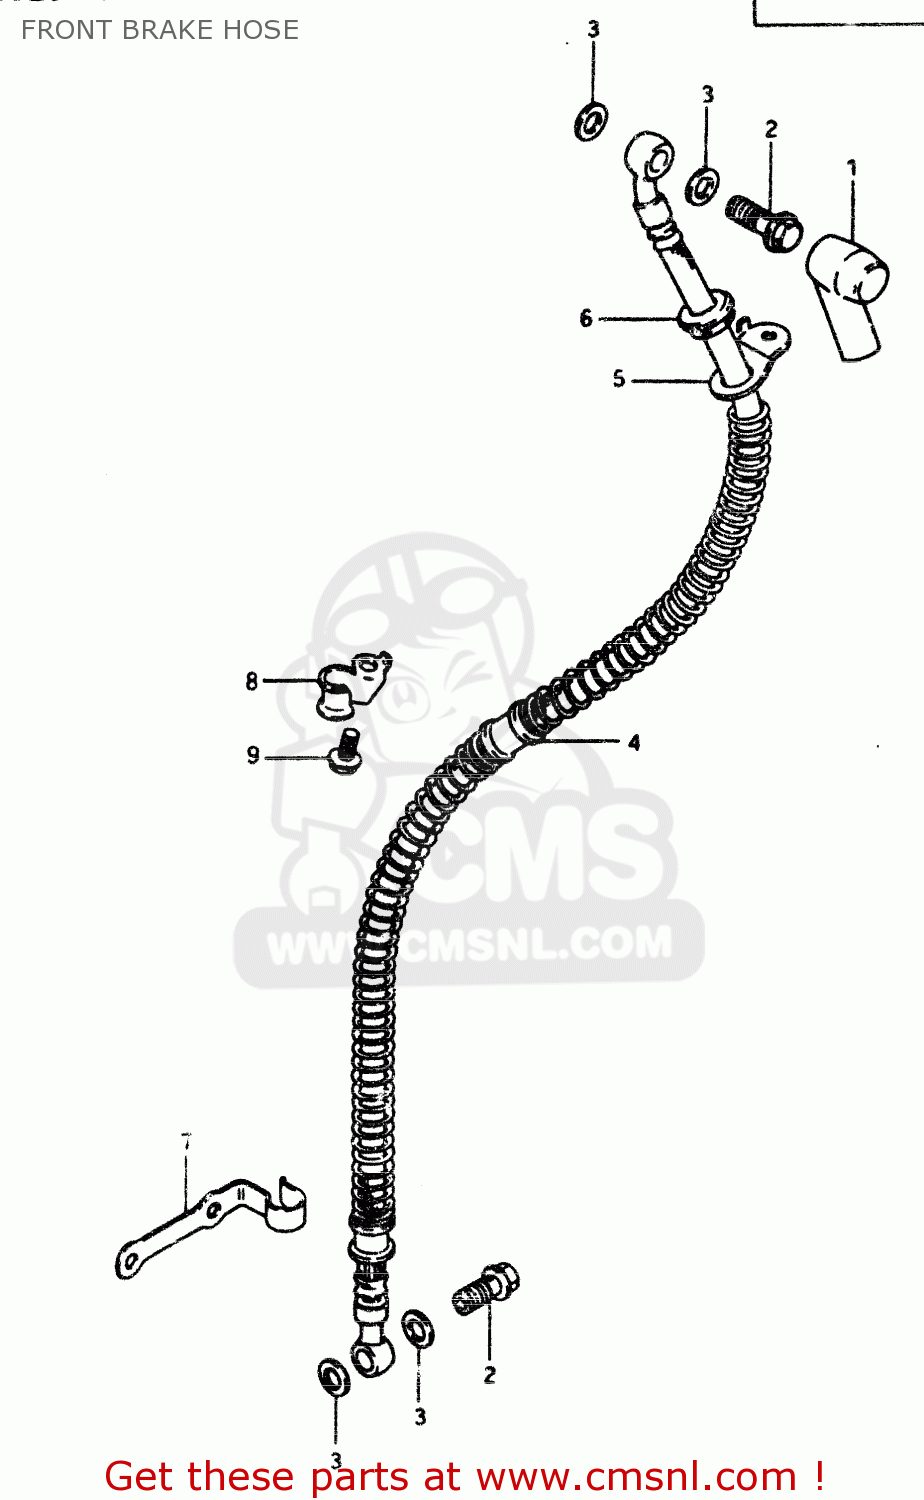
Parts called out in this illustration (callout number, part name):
1	BOOT,MASTER CYLINDER
2	BOLT UNION
3	WASHER
4	HOSE,FRONT BRAKE
5	GUIDE,BRAKE HOSE
6	GROMMET
7	GUIDE,BRAKE HOSE NO.2
8	GUIDE,BRAKE HOSE NO.3
9	BOLT
